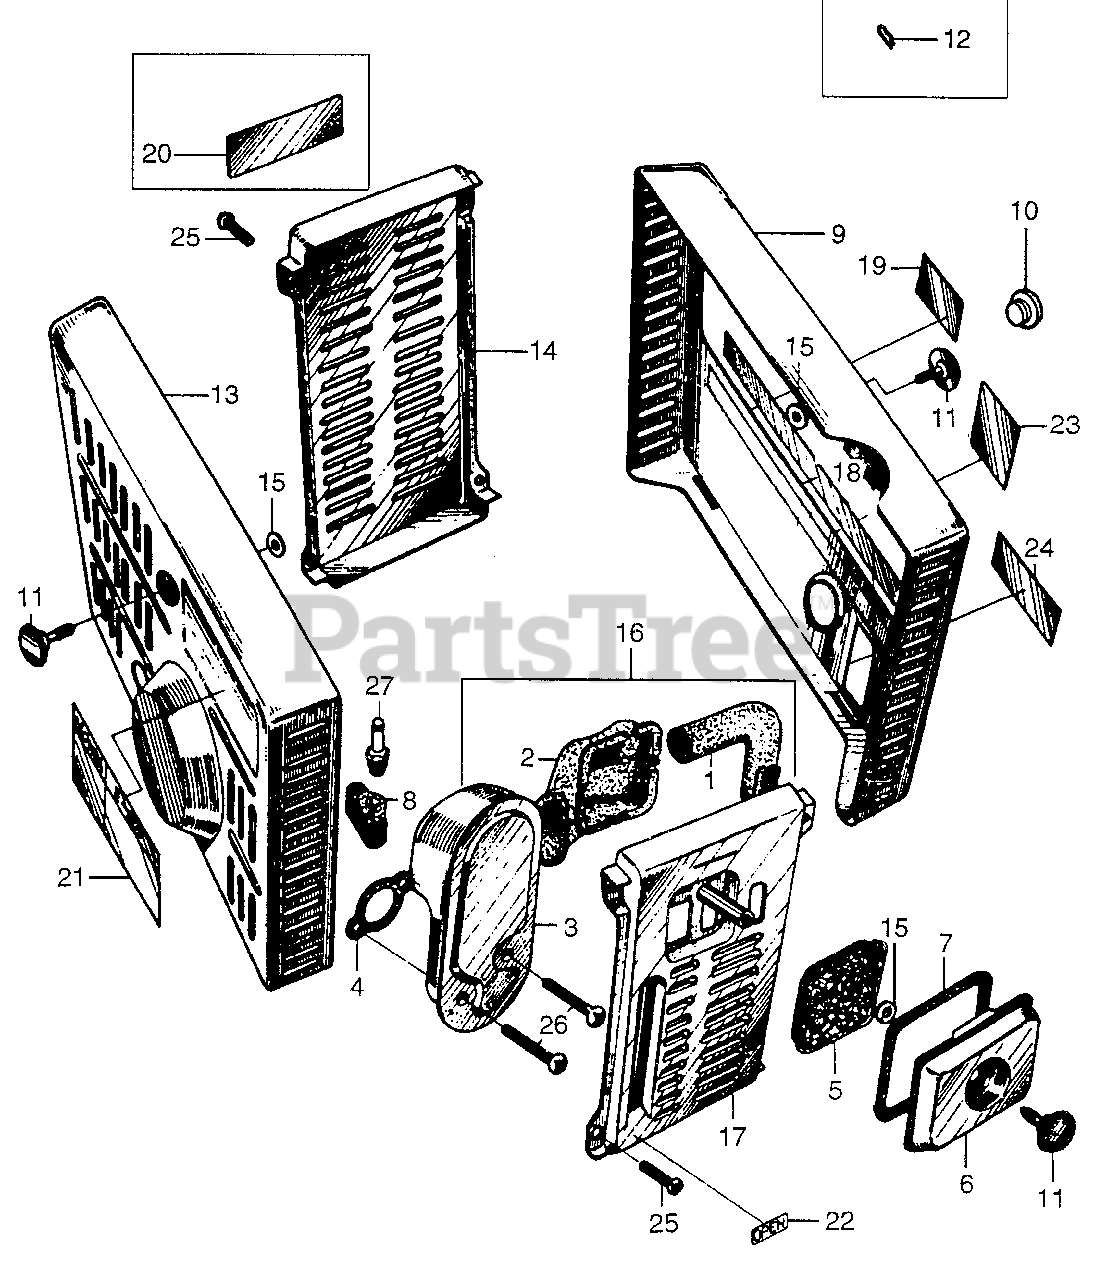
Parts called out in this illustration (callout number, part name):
1	TUBE, AIR CLEANER
1	TUBE, AIR CLEANER (NOT AVAILABLE)
2	TUBE, IN. MUFFLER CONNECTING
3	MUFFLER, IN. (NOT AVAILABLE)
4	GASKET, IN. MUFFLER (NOT AVAILABLE)
5	ELEMENT, AIR CLEANER
8	HOLDER, SPARE PLUG
9	COVER, FR. *R15L* (WINE RED)
11	LATCH, COVER
12	PIN, LATCH SNAP
13	COVER, RR. *R15L* (WINE RED)
14	COVER, R. SIDE
15	STOPPER, LATCH (NOT AVAILABLE)
17	COVER, L. SIDE
19	MARK, FR. (NOT AVAILABLE)
20	PLATE, NAME (NOT AVAILABLE)
20	PLATE, NAME
21	PLATE, CAUTION (NOT AVAILABLE)
23	MARK A, OIL CHECK
24	MARK B, OIL CHECK
25	SCREW, PAN (5X8)
26	SCREW, PAN (5X20)
27	SPARK PLUG (CM6) (NGK)
